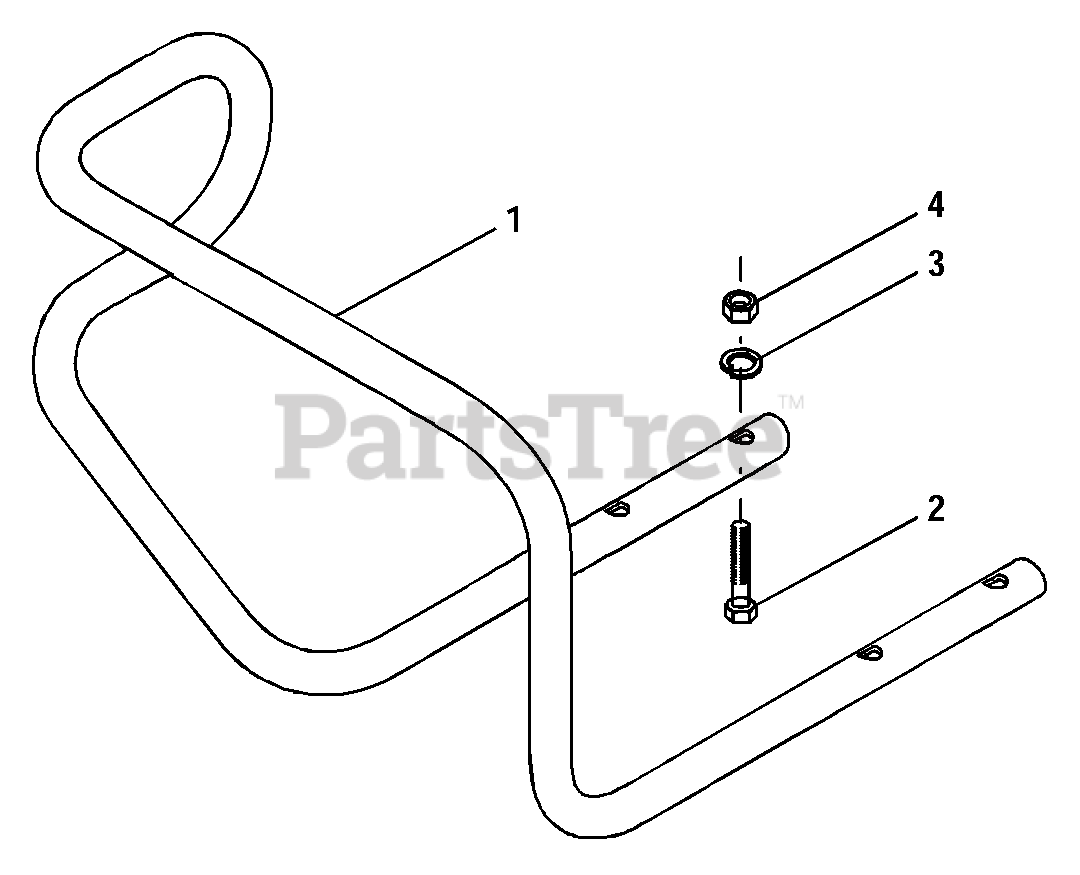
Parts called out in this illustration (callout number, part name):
1	Bumper
2	Hex Screw, 5/16-18 x 2-1/4
3	Nut, Hex, 5/16-18
4	Lock Washer, 5/16
